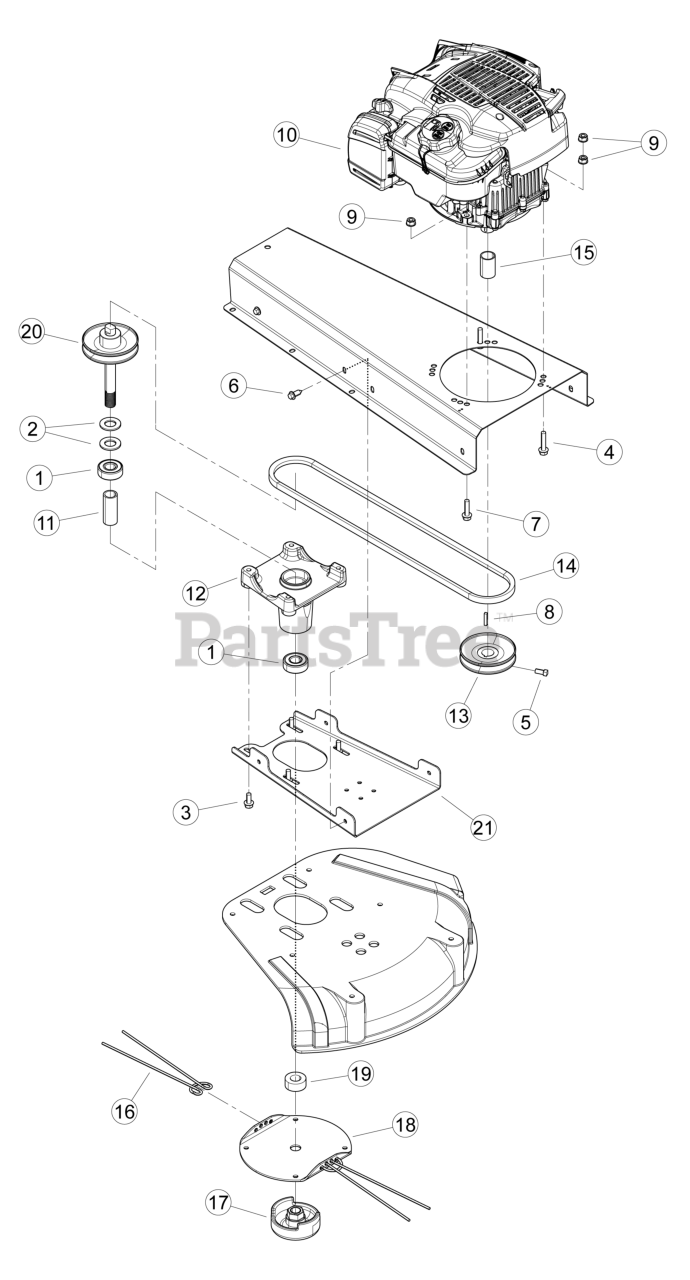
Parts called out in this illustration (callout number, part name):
1	BEARING, 3/4 BALL
2	WASHER, 3/4" SAE FLAT ZP
3	BOLT, 5/16 × 3/4 FLANGE NC
4	BOLT, 5/16 × 1-1/2 FLANGE NC
5	SCREW, 5/16-18 × 5/8 SQ HD SET
6	SCREW, 11/32-12 × 7/8 FLANGE T-AB
7	BOLT, 5/16 × 1-1/4 FLANGE NC
8	KEY, 3/16" × 1.00" LG SQUARE
9	NUT, 5/16-18 NYLOCK FLANGE
10	ENGINE, BRIGGS 163cc VERTICAL
11	SPACER, TRIMMER SPINDLE
12	CASTING, TRIMMER SPINDLE HUB
13	PULLEY, ENGINE 4.0 × .875 B GROOVE
14	BELT, AX48
15	SPACER, 1-1/16 OD × 14 GA × 1.630
16	STRING, 20" × .155 DIA. CROSS-FIRE
17	MOWBALL, CAST TRIMMER PAINTED
18	DISK, TRIMMER HEAD
19	SPACER, TRIMMER HEAD
20	WELDMENT, SPINDLE HW MODELS
21	PLATE, SPINDLE CASTING MOUNT
